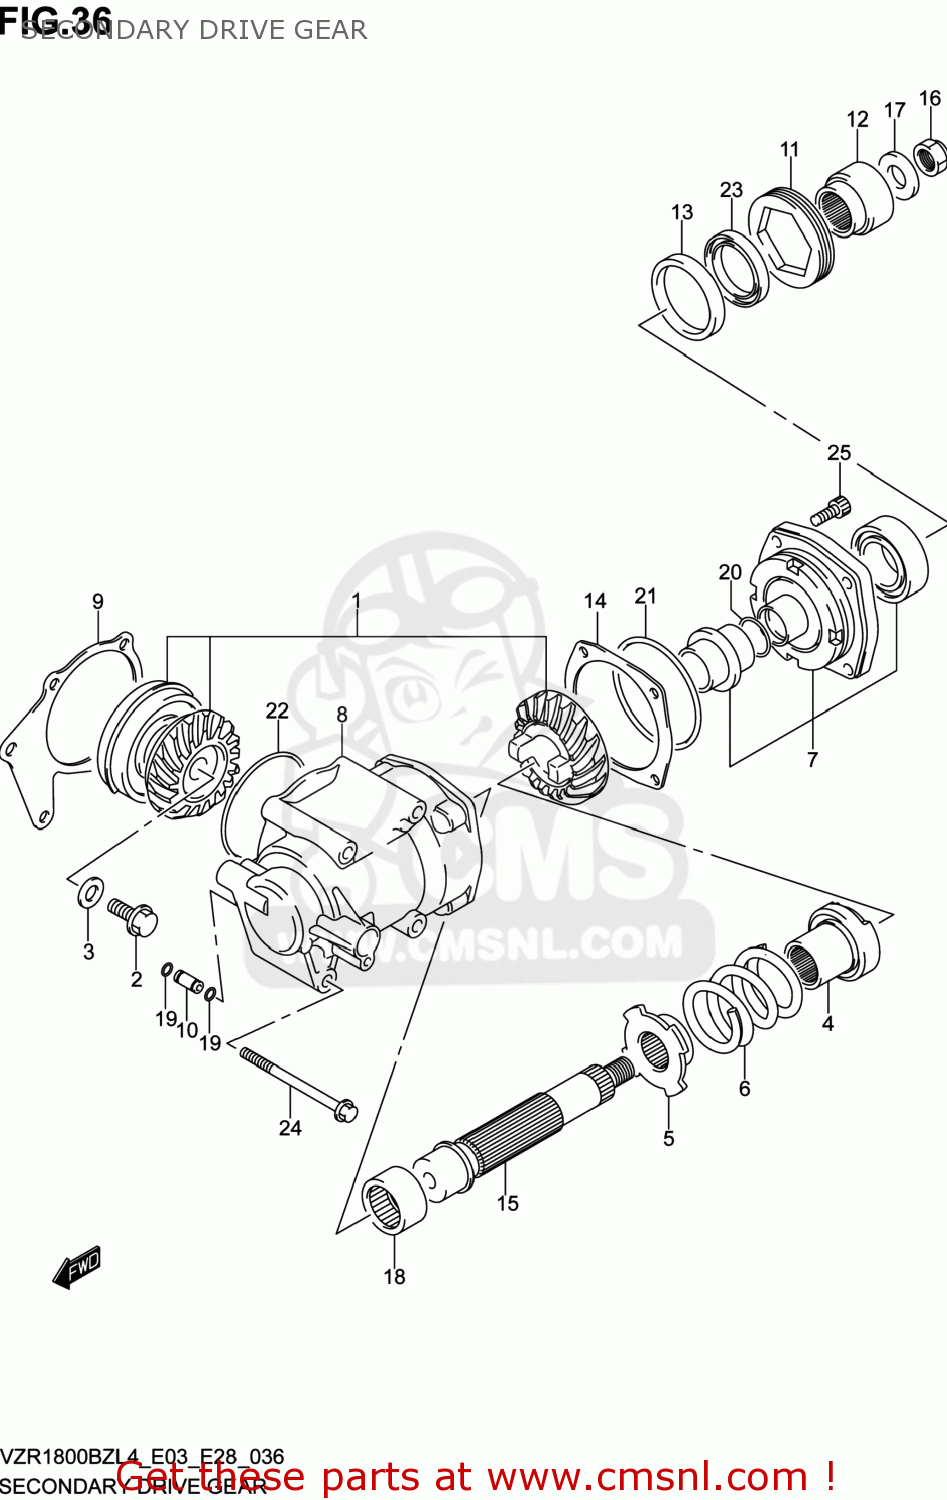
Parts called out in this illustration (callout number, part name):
1	GEAR SET,SECONDARY
2	BOLT(12X24)
3	WASHER(12X35X2)
4	DOG,OUTPUT CAM
5	STOPPER,CAM SPRING
6	SPRING,SECONDARY DAMPER
7	STOPPER SECONDARY SET,DRIVEN
8	CASE,SECONDARY GEAR
9	SHIM SET,SEC DRIVE
10	PIPE,SECONDARY CASE OIL
11	STOPPER,SEC DRIVEN BEARING
12	COUPLING,SEC DRIVEN BEVEL
13	HOUSING,OIL SEAL
14	SHIM SET,SECONDARY DRIVEN
15	SHAFT,SECONDARY DRIVEN
16	NUT
17	WASHER(16.5X36X4)
18	BEARING(32X48X22)
19	O RING(D:1.7,ID:6)
20	O RING(D:2.4,ID:23.7)
21	O RING(D:3.7,ID:76.5)
22	O RING(D:2.4,ID:90.8)
23	SEAL,OIL(38X54X6)
24	BOLT
25	BOLT(10X30)
